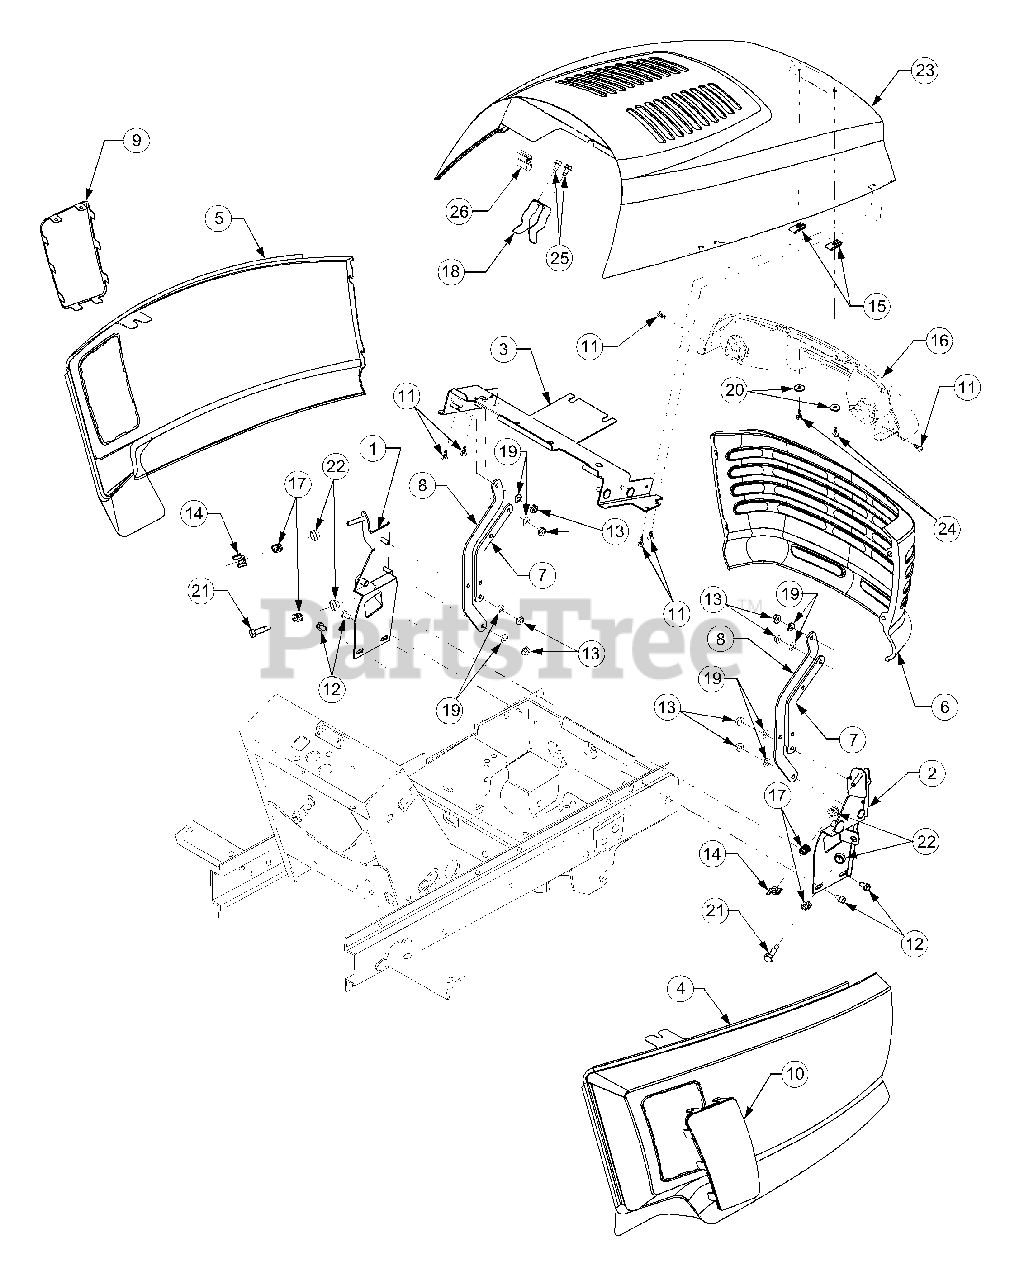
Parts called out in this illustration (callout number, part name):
1	Bracket, Grille LH
2	Bracket, Grille RH
8	Link, Long Hood
12	Screw, Hex Wash Hd Tapp, 1/4 x .50
13	Nut, Hex Flange Lock, 1/4-20
14	Nut, Wing, 1/4-20
15	Nut, U-Type Speed, #10
16	Headlight Assy
17	Spring, Compression, .50 OD x .50
18	Spring, Hood Latch
19	Washer, Spring, .265 x .562 x .025
20	Washer, Flat, .218 x .62 x .063
21	Bolt, Shoulder, .31 Dia x .75 Lg
22	Bushing, Tapered
23	Hood, Series 2000
24	Screw, Hex Tapp, 10-16 x .625
25	Screw, Hex Wash Hd Tapp, 1/4-14 x .5
26	Seal, Heat Baffle
